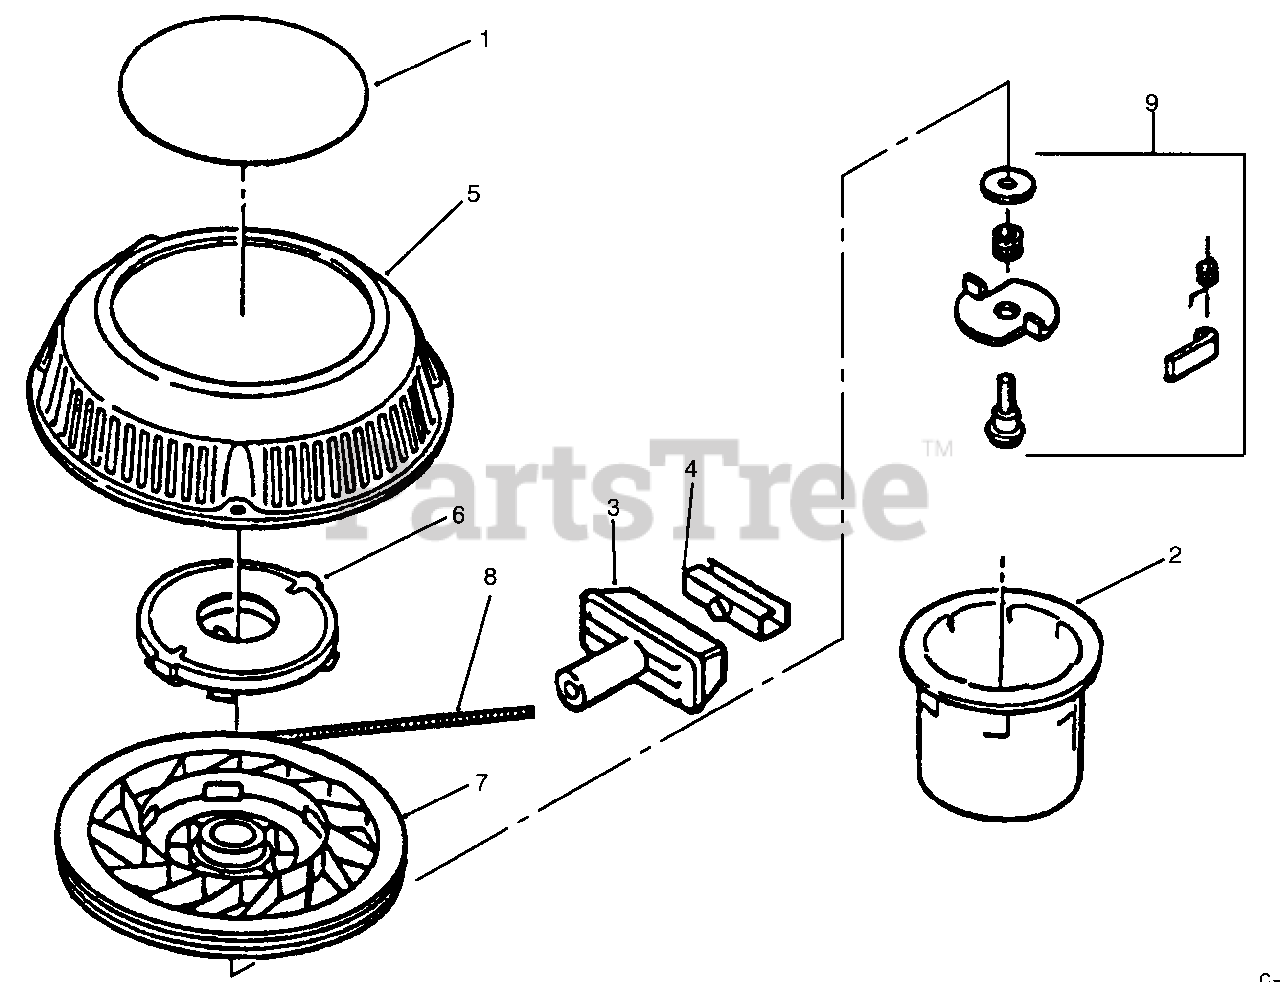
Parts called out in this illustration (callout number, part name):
1	Decal-Model No. 10590
1	Decal-Model No. 10591
2	Hub-Starter
3	Handle-Starter
4	Insert-Clip, Rope
5	Housing-Starter
6	Recoil Spring & Keeper
8	Rope
9	Assembly-Dog Kit
